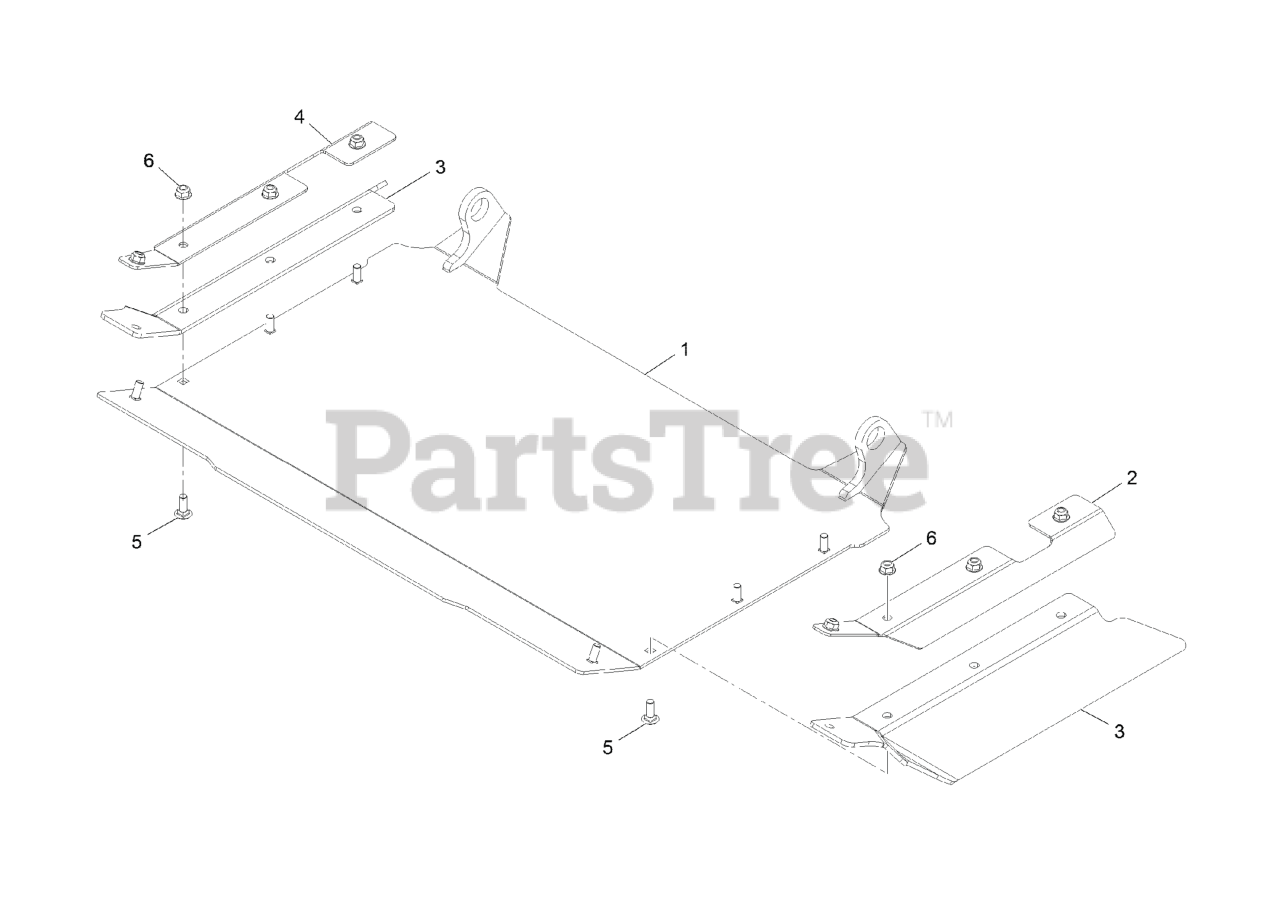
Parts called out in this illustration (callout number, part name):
1	Discharge-Tunnel 72 [black]
2	Bracket-Flap, LH
3	FLAP-RUBBER
4	Discharge-Tunnel 72 [black]
5	SCREW-CARR
6	NUT-HF, NI
